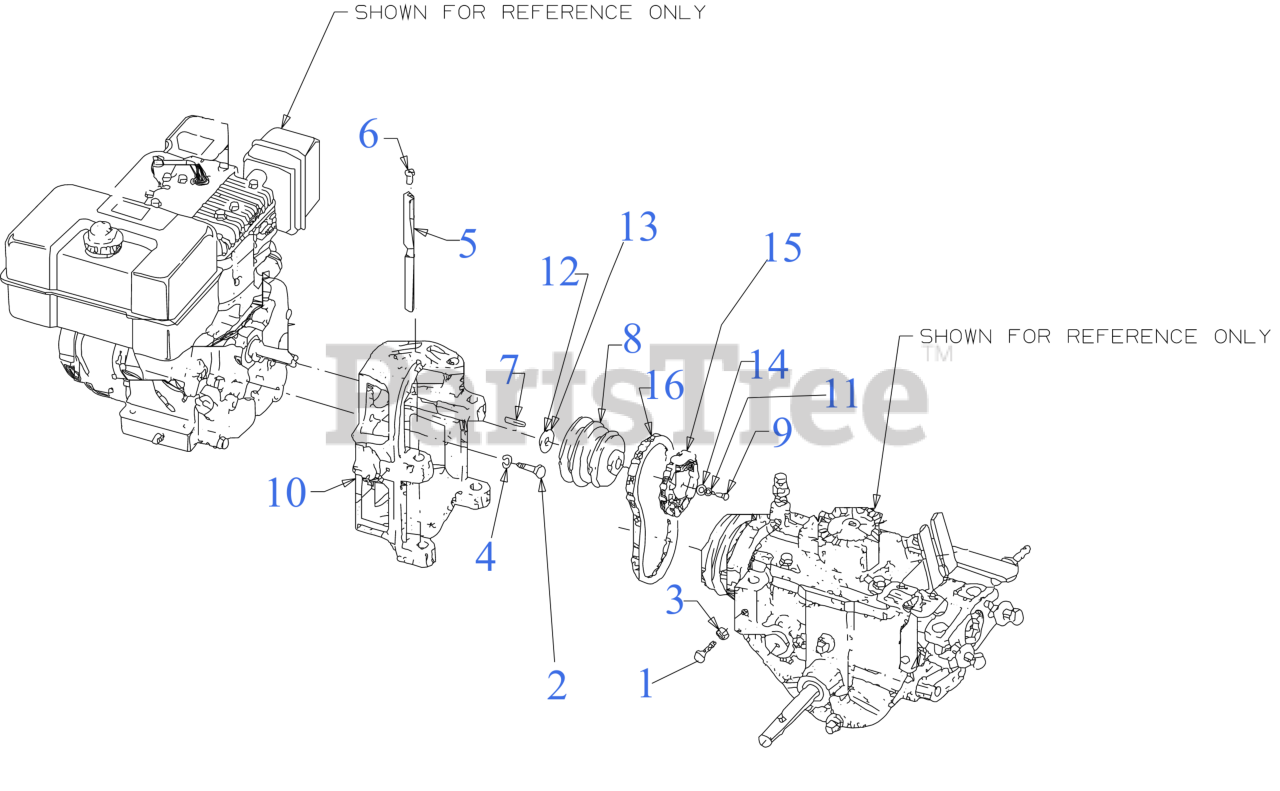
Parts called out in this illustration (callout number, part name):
1	SCREW 5/16-18 x 1.0 GR5
2	SCREW 5/16-24 x 1.25 GR5
3	HEX NUT 5/16-18
4	FLAT WASHER 344X1.00
5	ENGINE MOUNTING BAR
6	PLUG-CAP (RED)
8	SCREW 3/8-24 x 1.75 GR5
9	MOTOR MOUNT (POWDER BLACK)
10	LOCK WASHER 3/8
11	SHIM 1.0X.7656X.062
12	FLAT WASHER .766 x 1.000 x .031
13	FLAT WASHER .406ID X1.0 OD
14	REVERSE DISC
15	DRIVE BELT FORWARD 22.14''
